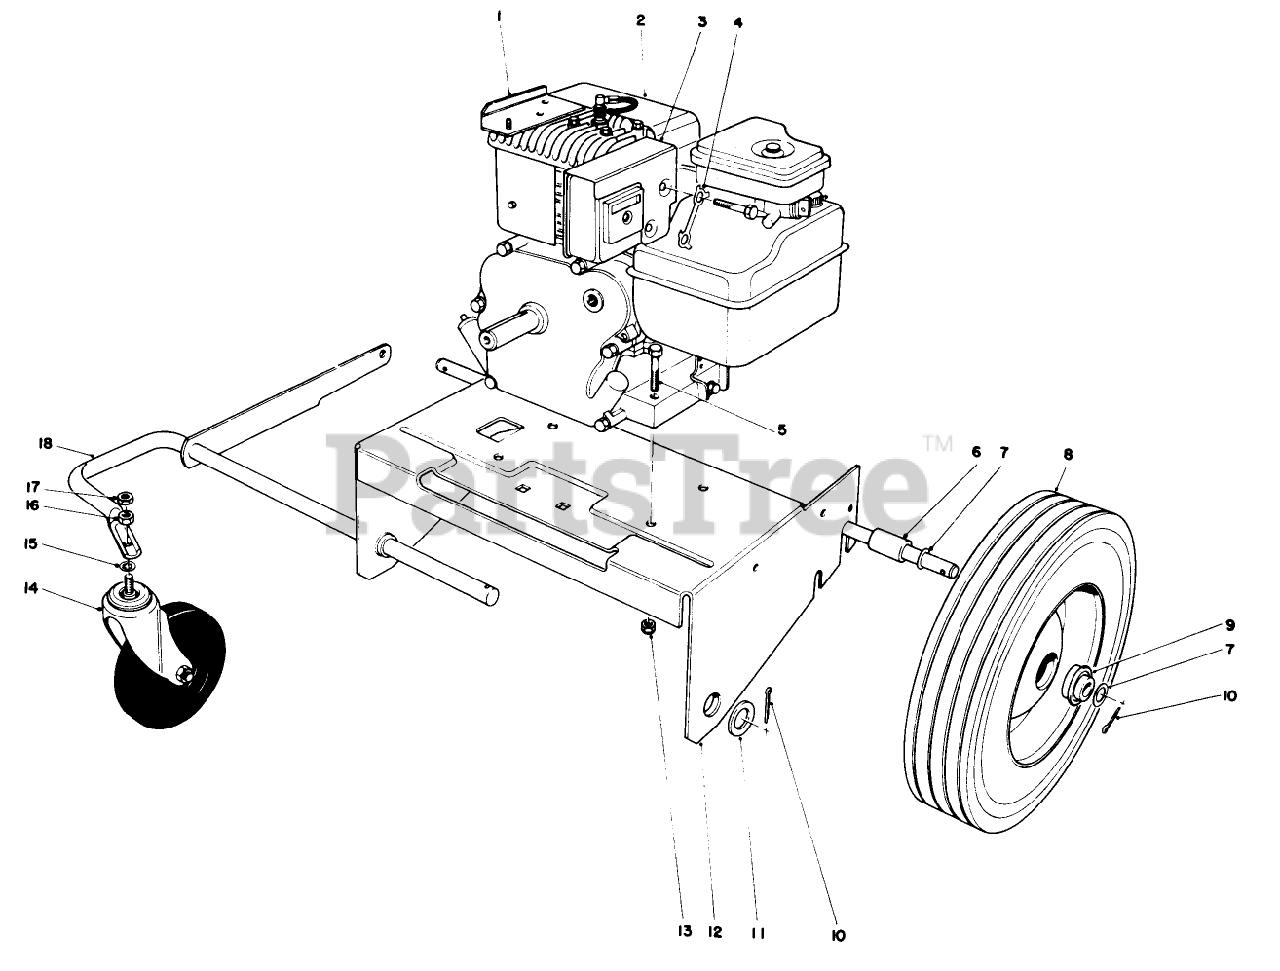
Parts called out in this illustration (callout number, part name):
2	Engine
5	SCREW-HH
6	SPACER-AXLE
7	WASHER
8	WHEEL
9	BEARING
10	PIN-COTTER
11	WASHER-FLAT
13	NUT-LOCK, CONE
14	CASTER
15	WASHER-LOCK/INT
16	NUT-HH
